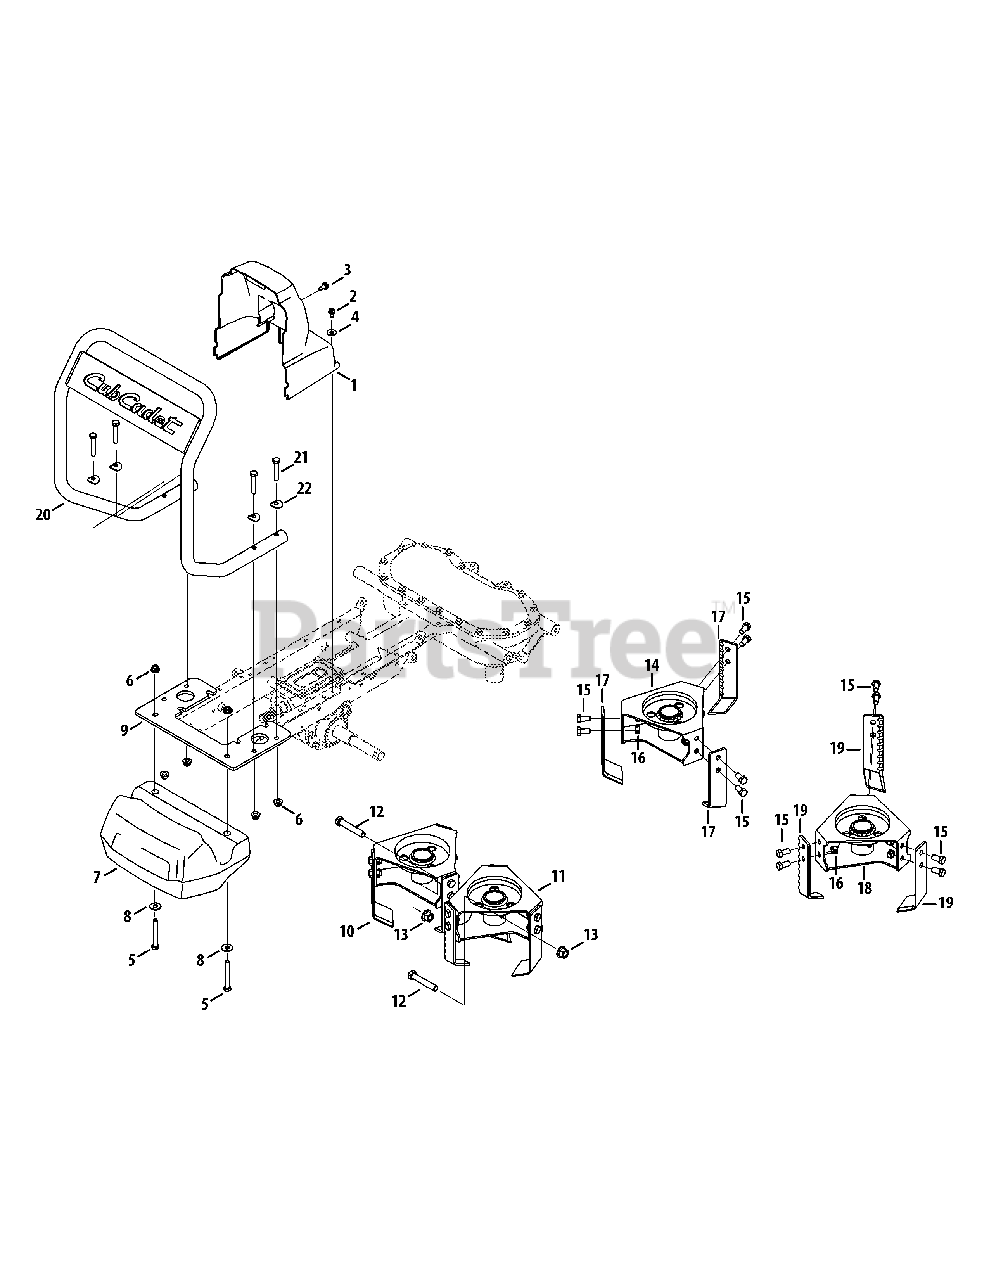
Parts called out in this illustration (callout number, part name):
1	Belt Cover
2	Screw, 1/4-20 x 0.500
3	Self Tapping Screw, 1/4-14 x .625
4	Washer, Flat, .28 x .74 x .063
5	Hex Screw, 5/16-18, 2.50, Gr5
6	Flangelock Nut, 5/16-18, B&S
8	Flat Washer, .349 x .879 x .063
9	Bumper Mounting Plate
10	Tine Assembly, RH
11	Tine Assembly, LH
12	Hex Cap Screw, 7/16-20 x 2.5 (Grade 5)
13	Flange Lock Nut, 7/16-20
14	Tine Bracket, RH
15	Hex Cap Screw, 3/8-16 x .75
16	Hex Lock Nut, 3/8-16
17	Tine Blade, RH
18	Tine Bracket, LH
19	Tine Blade, LH
21	Hex Cap Screw, 5/16-18 x 1.75
22	Saddle Washer, .320 x .93 x .060
